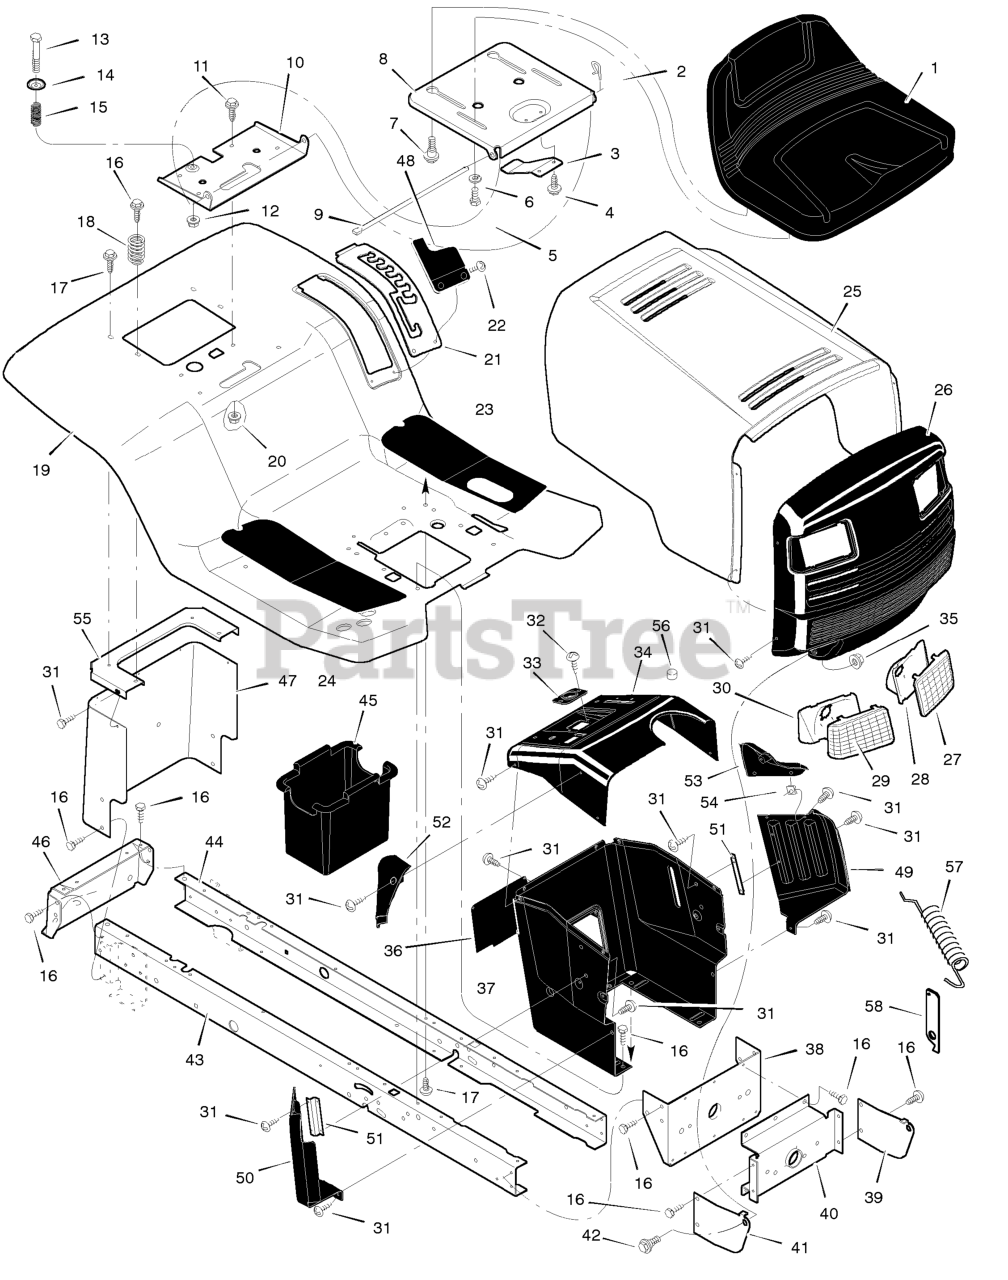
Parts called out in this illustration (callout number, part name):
2	Cap, Push On
5	Bolt, Wing
6	Washer
7	Bolt, Shoulder
8	Support, Seat
9	Rod, Pivot
10	Bracket, Pivot
11	Bolt
13	Bolt, Shoulder
15	Spring
19	Deck, Seat
20	Nut
21	Plate, Index
23	Mat, Left
24	Mat, Right
27	Lens, Left
28	Bezel, Left
29	Lens, Right
30	Bezel, Right
31	Screw
33	Bearing, Steering
35	Nut
36	Panel, Access
37	Support, Dash
38	Bracket, Rear Hanger
39	Support, Left Grille
40	Axle, Hanger
41	Support, Right Grille
42	Bolt, Shoulder
43	Frame, Right
44	Frame, Left
45	Container, Battery
46	Plate, Hitch
47	Panel, Rear
48	Cover, Level Adjustment
49	Panel, Left Side
50	Panel, Right Side
51	Bracket, Panel
52	Cap, Panel
53	Cap, Left Panel
54	Retainer
55	Plate, Rear
56	Bumper
57	Extension, Spring
58	Bracket
